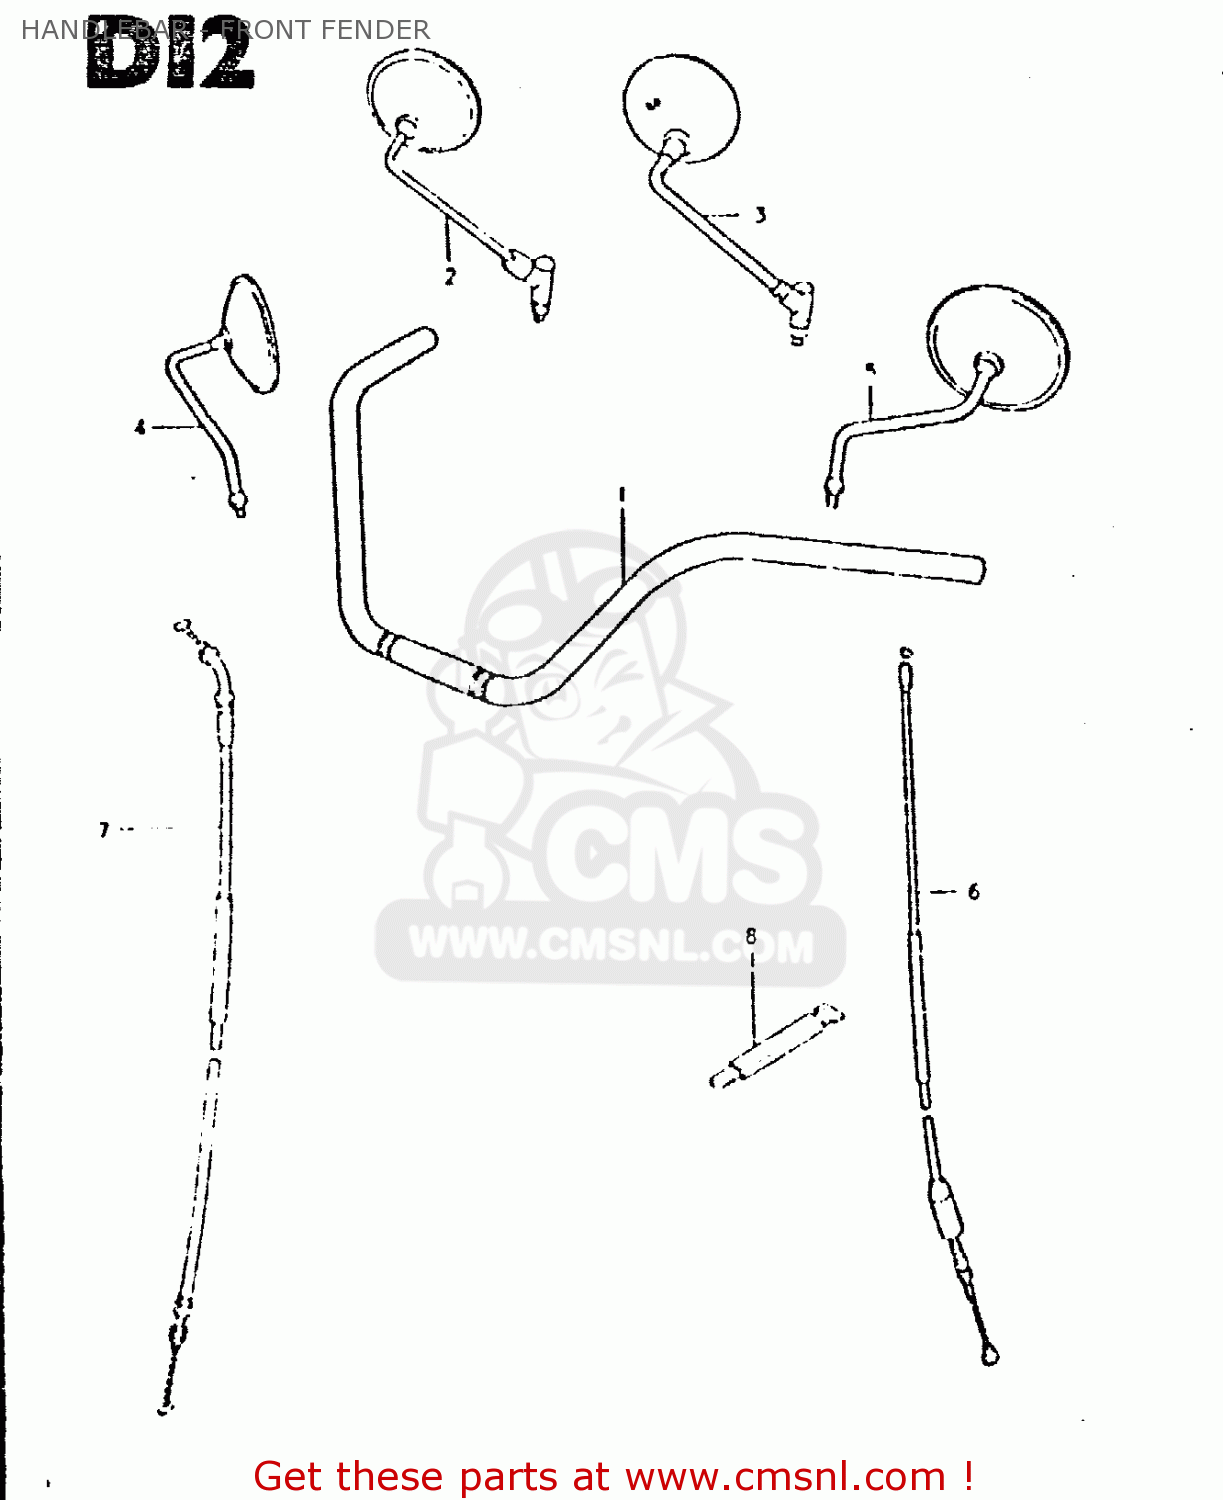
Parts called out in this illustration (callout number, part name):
1	HANDLEBAR
2	MIRROR ASSY,RH
6	CABLE ASSEMBLY,CLUTCH
7	CABLE ASSEMBLY,THROTTLE
8	CLAMP
